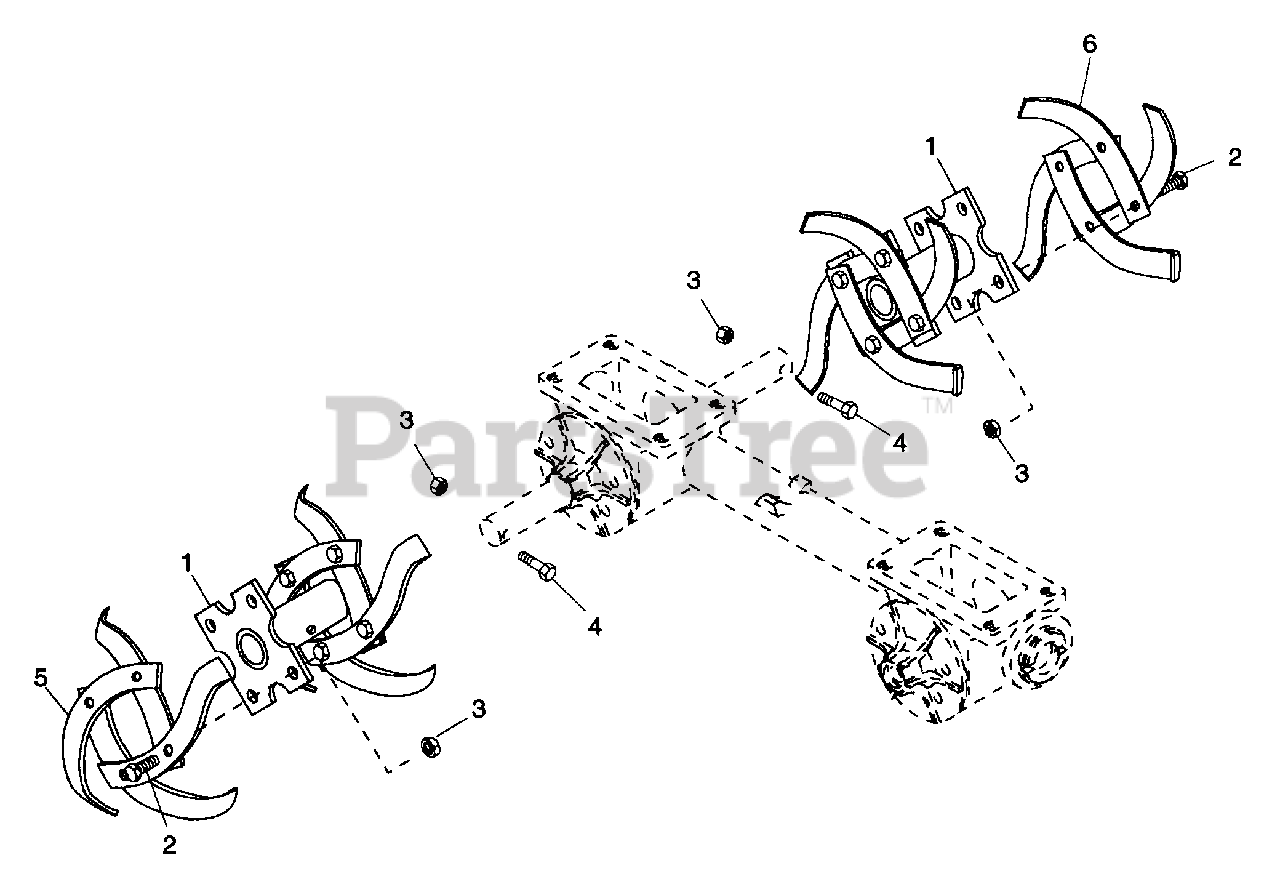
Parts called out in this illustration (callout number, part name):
1	HOLDER - BOLO TINE WLDM'T
2	BLT-HEX .38-16X1.00 PL GR5
3	NUT-LK-JAM-CTR .375-16 PL
4	SCR-CAP .38-16X1.75 GR8
5	R H BOLO TINE
6	L H BOLO TINE
